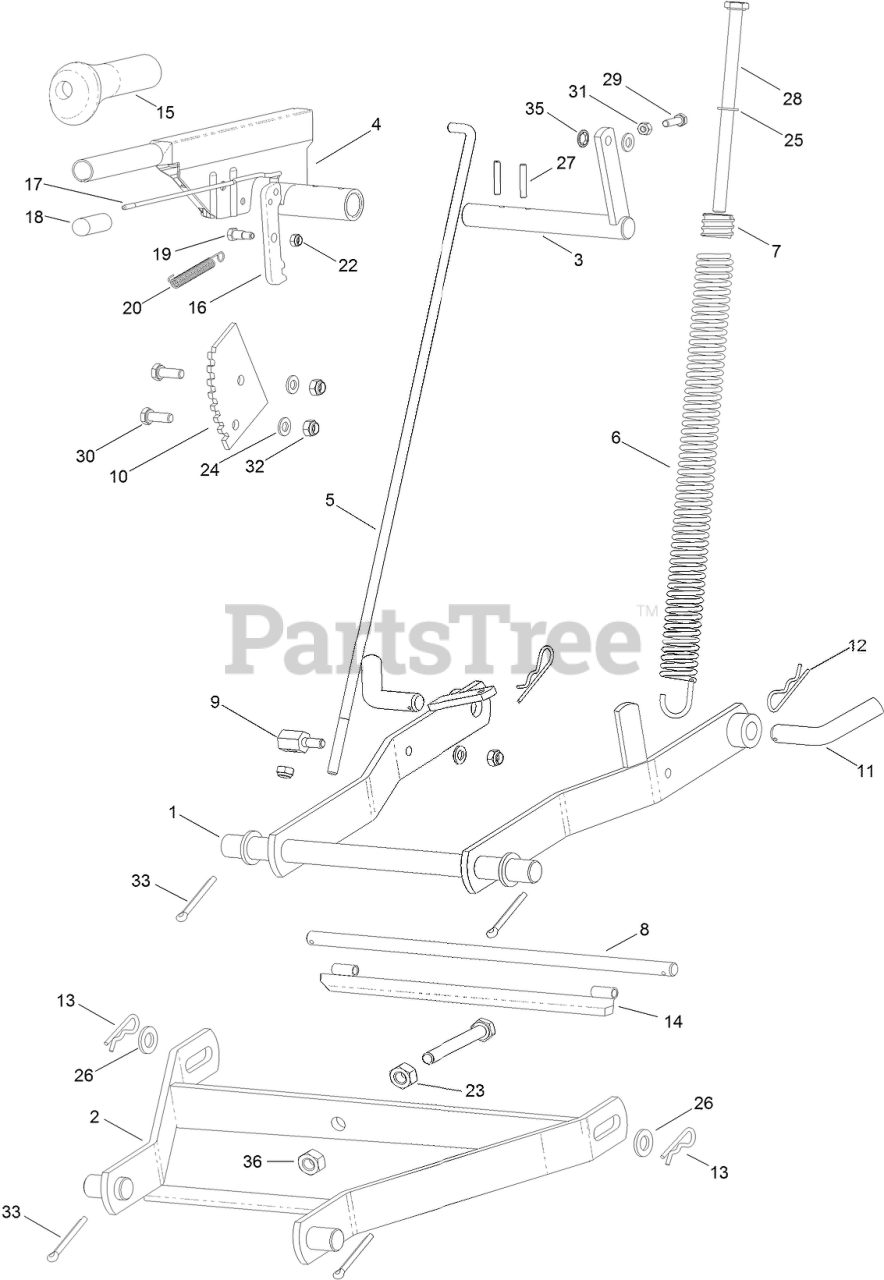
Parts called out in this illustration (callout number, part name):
1	SUSPENSION-DECK, MOWER
2	SUSPENSION-MOWER DECK, FRONT
3	SHAFT-ADJUSTMENT, HEIGHT
4	LEVER-ARM, HEIGHT ADJUST
5	ROD-ADJUSTMENT, HEIGHT
6	SPRING
7	NUT-SPRING
9	TRUNNION
10	SEGMENT-GEAR
11	PIN-BENT
12	PIN-HAIR
13	PIN-HAIR
14	HOLDER-FRONT
15	GRIP-HANDLE
16	RATCHET-PLATE, PIVOT
17	ROD-CONNECTION
18	BUTTON-PLUNGER
19	SCREW-LEVER
20	SPRING
22	NUT-LOCK
23	NUT-HEX
24	WASHER-PLAIN
25	WASHER-FLAT
26	WASHER-FLAT
27	PIN-SPRING
28	SCREW M10X180
29	SCREW-HH
30	SCREW-HH
31	NUT-HEX
32	NUT-LOCK, NI
33	PIN-COTTER
35	WASHER
36	NUT-LOCK, HEX NI
